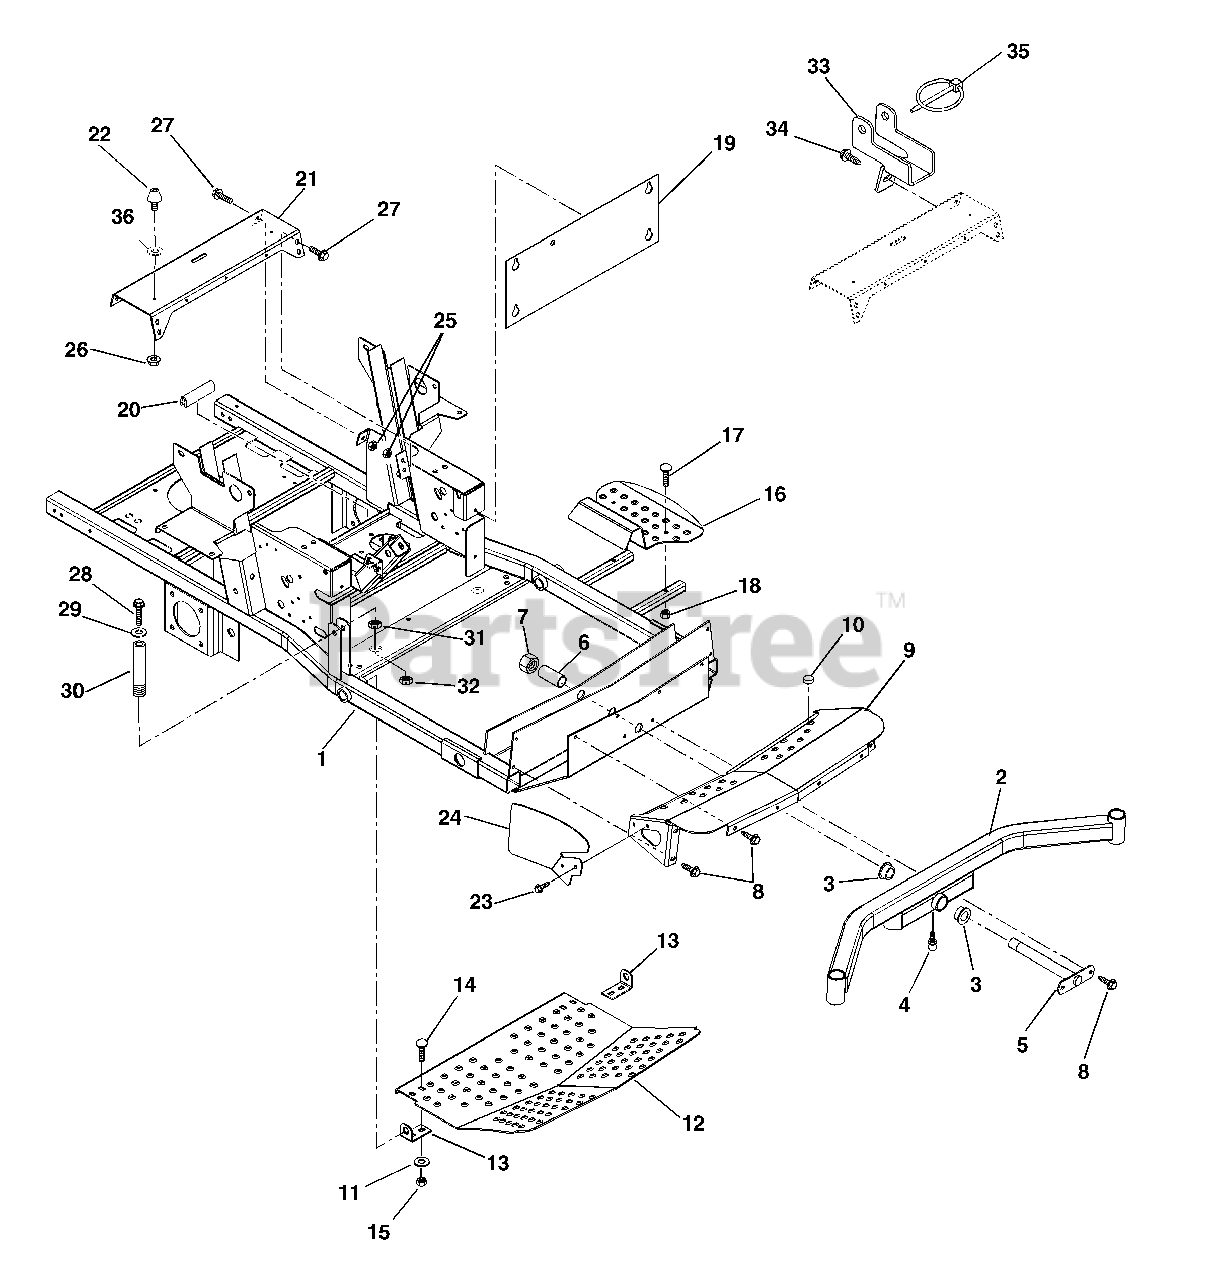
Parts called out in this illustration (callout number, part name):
2	Axle-Front
3	Bushing-Flange 1.020 x 1.385 x .75 x 1.75
4	Fitting-Lube .25-28 x .256
5	Pin-Axle
7	Nut-Locking-Nylon 1.0-14
8	Screw-Tapping .38-16 x .75
9	Cover-Axle
10	Button Bumper
11	Washer-Flat-Steel .38 x .875 x .083
12	Panel-Inspection
13	Mount-Inspection Panel
14	Bolt-Round Head Square Neck .38-16 x 1.00 Grade 5
15	Nut-Locking-Nylon .38-16
16	Step-Ingress
17	Bolt-Round Head Square Neck .31-18 x 1.50 Grade 5
18	Nut-Locking-Center .31-18
19	Plate-Kick
20	Strip -Cowl
21	Channel-Cross
23	Screw-Tapping .25-20 x .50 Hex Washer Head
24	Cover, Cylinder Rod End
25	Nut-Retainer .375-16 x .37
26	Nut-Locking-Flange .312-24
27	Bolt-Serrated Flange Washer Head .38-16 x 1.00
28	Bolt-Hex .50-20 x 1.00 Grade 5
29	Washer-Flat-Steel .531 x 1.06 x .095
30	Post
31	Nut-Jam .75-16
32	Nut, Jam Center-Lock .75-16
33	Bracket, Seat Lock
34	Screw-Tapping .25-20 x .50 Hex Washer Head
35	Pin-LOK .31 x 2.00
36	Washer-Flat-Steel .38 x.87 x .179
